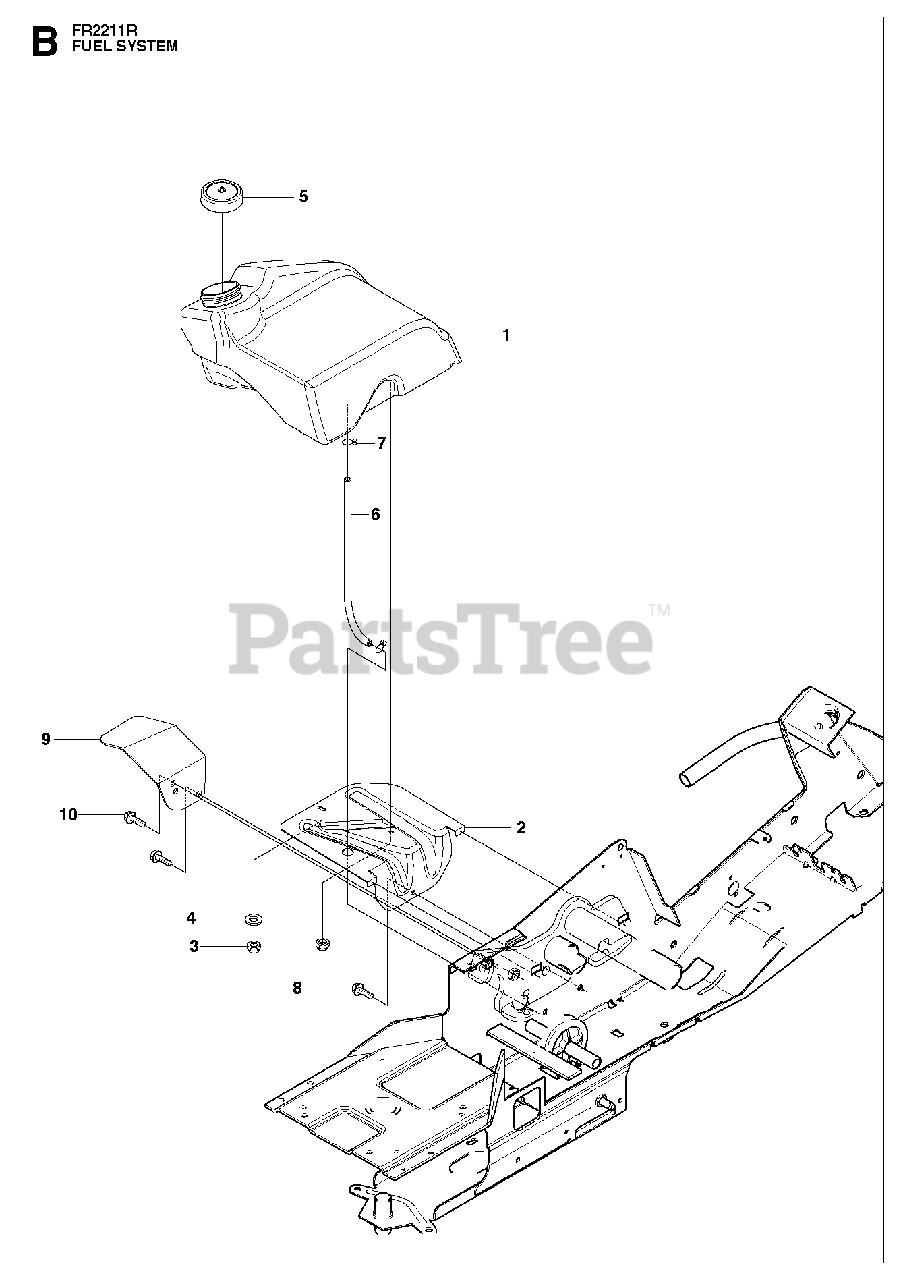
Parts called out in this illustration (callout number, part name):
3	LOCKNUT M6
4	WASHER
10	SCREW M10X25
